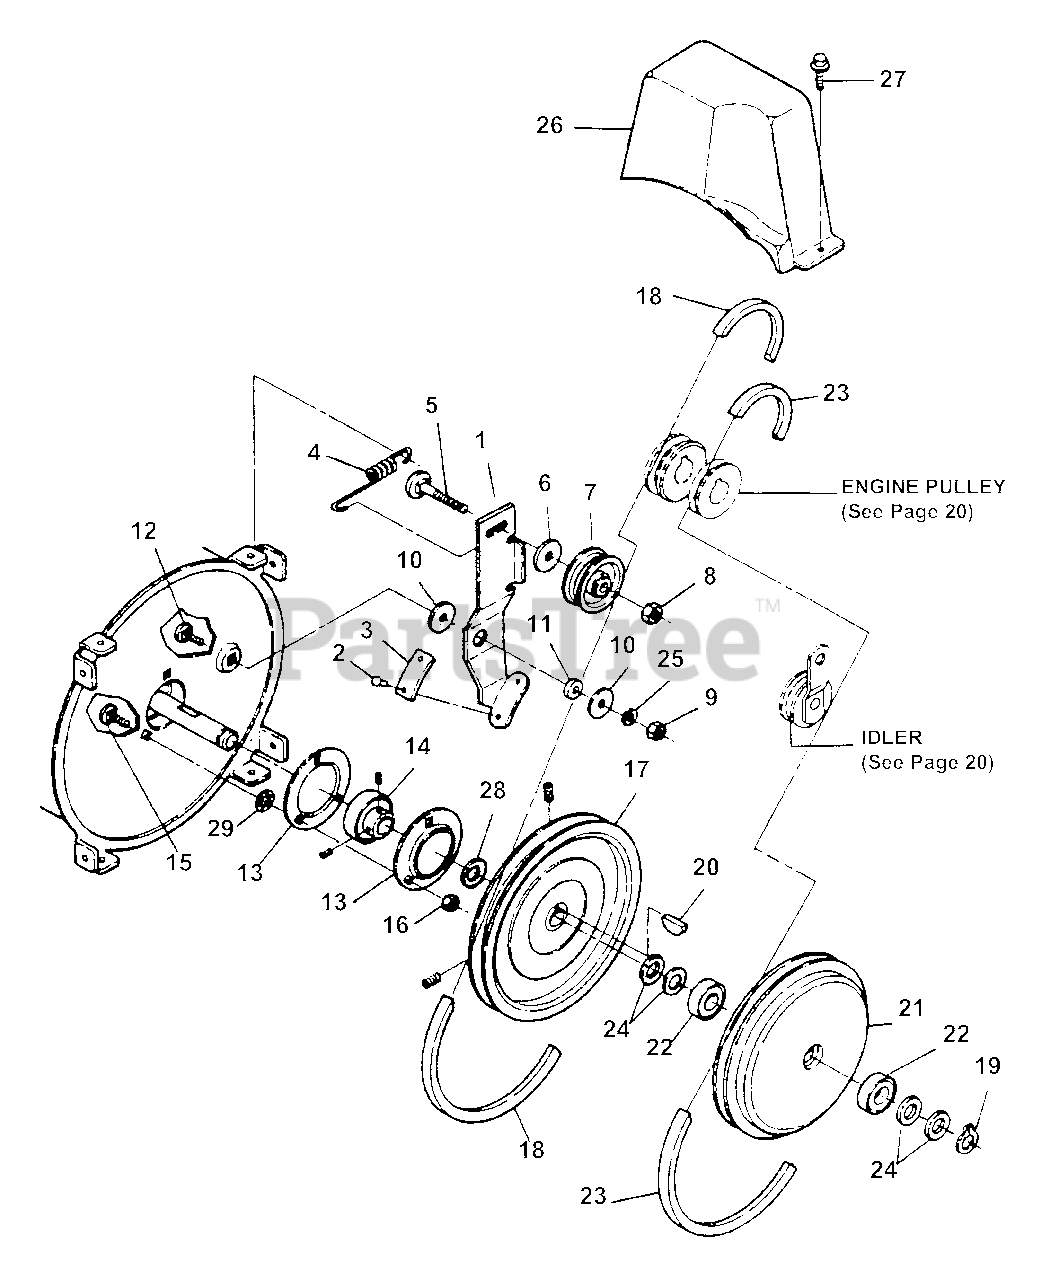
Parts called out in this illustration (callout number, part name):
1	ASSEMBLY, Idler Arm
2	RIVET
3	PAD, Brake
4	SPRING
5	BOLT, 3/8-16 x 1-1/2" Square Neck Carriage, Grade 2
6	WASHER, 3/8" Flat
7	PULLEY, Idler
8	NUT, 3/8-16 Hex Top Lock
9	NUT, 5/16-18 Hex, Grade B or 5
10	WASHER, 5/16 x 1-1/4" Flat
11	SPACER
12	BOLT, 5/16-18 x 1" Square Neck Carriage, Grade 5
13	HOUSING, Bearing
14	BEARING
15	BOLT, 5/16-18 x 3/4" Short Neck Carriage, Grade 5
16	NUT, 5/16-18 Hex Flange Lock, Grade 5
17	SHEAVE, Blower
18	V-BELT (4L, 38.5"), Blower
19	RING, 1/2 External Snap (Heavy Duty)
20	KEY, 3/16 x 7/8" Woodruff
21	PLATE, Drive
22	BEARING, Ball
23	V-BELT (3L, 37.75"), Traction
24	WASHER, 1/2 Shim (4)
25	WASHER, 5/16 Split Lock
26	COVER, Belt Guard
27	SCREW, 1/4-20 x 1/2" Hex Washer Self-Tap
28	WASHER, 3/4 x 1-1/8" Flat
29	RETAINER, 5/16 Bolt
